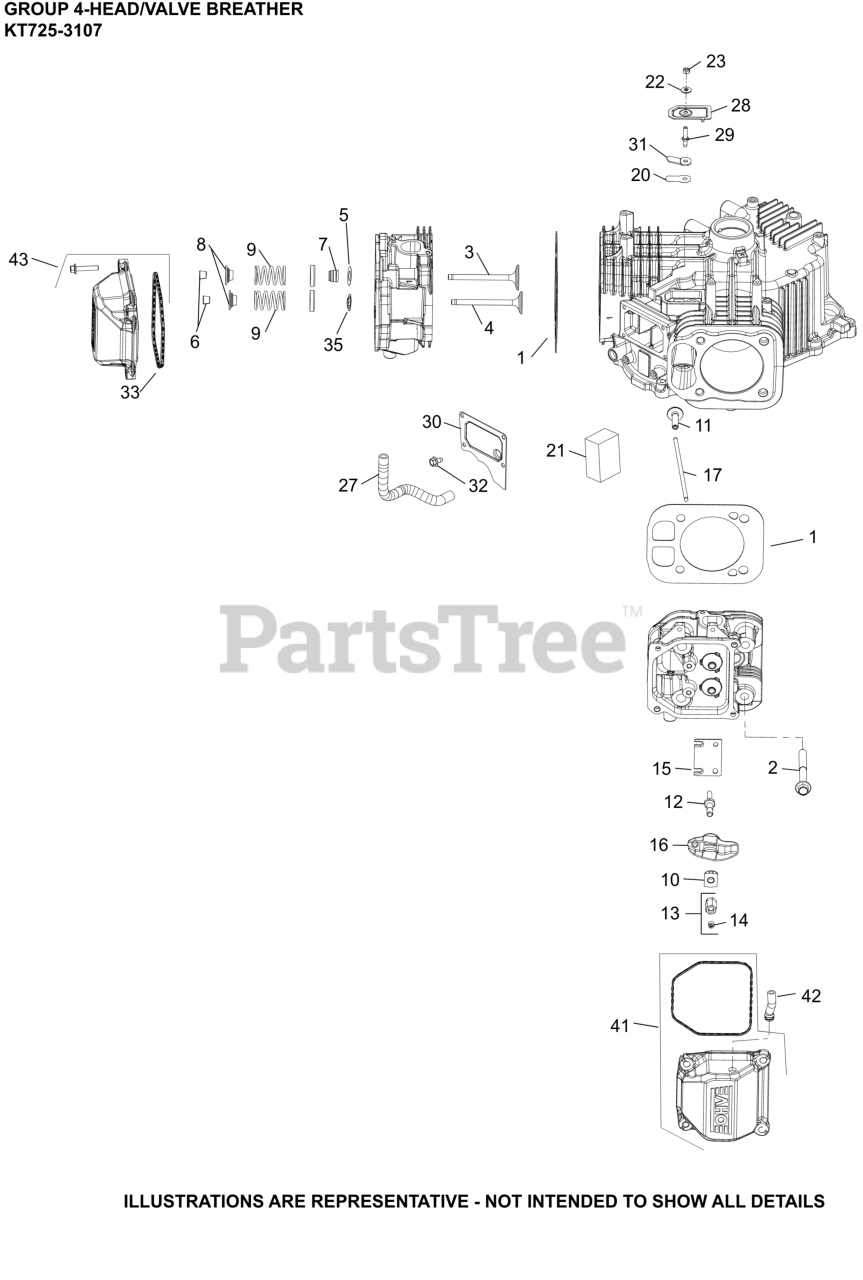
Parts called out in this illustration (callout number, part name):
1	KIT, CYLINDER HEAD GASKET
2	SCREW, HEX FLANGE M10 X 1.5-6g X 90mm
3	VALVE, INTAKE
3	VALVE, INTAKE (.25) - (#2401702S)
4	VALVE, EXHAUST
4	VALVE, EXHAUST (.25)
5	SPACER (.010")
6	KIT, RETAINER
7	SEAL, VALVE BAND
8	CAP, VALVE SPRING
9	SPRING VALVE
10	PIVOT, ROCKER ARM
12	STUD, ROCKER
13	HEX NUT ASSEMBLY
14	SCREW, SET
15	PLATE, GUIDE
16	ARM, ROCKER
17	ROD, PUSH
20	REED, BREATHER
21	FILTER, BREATHER
22	WASHER, SEALING
23	NUT, LOCK M5X.8
27	HOSE, BREATHER
28	COVER, BREATHER REED
30	COVER, BREATHER MEDIA
31	RETAINER, REED
32	SCREW, THREAD FORMING
33	O-RING (YELLOW), VALVE CO
35	RETAINER, VALVE GUIDE (KM)
41	KIT,BREATHER VALVE COVER (PLASTIC)
42	HOSE, FP-USE 32 326 07-S(PLASTIC COVERS)
43	KIT, VALVE COVER-PLAIN (PLASTIC)
NI	SCREW, HEX FLANGE (M6 X 31.625 DOG PT)
NI	KIT, #1 CYLINDER HEAD
NI	KIT, #2 CYLINDER HEAD
